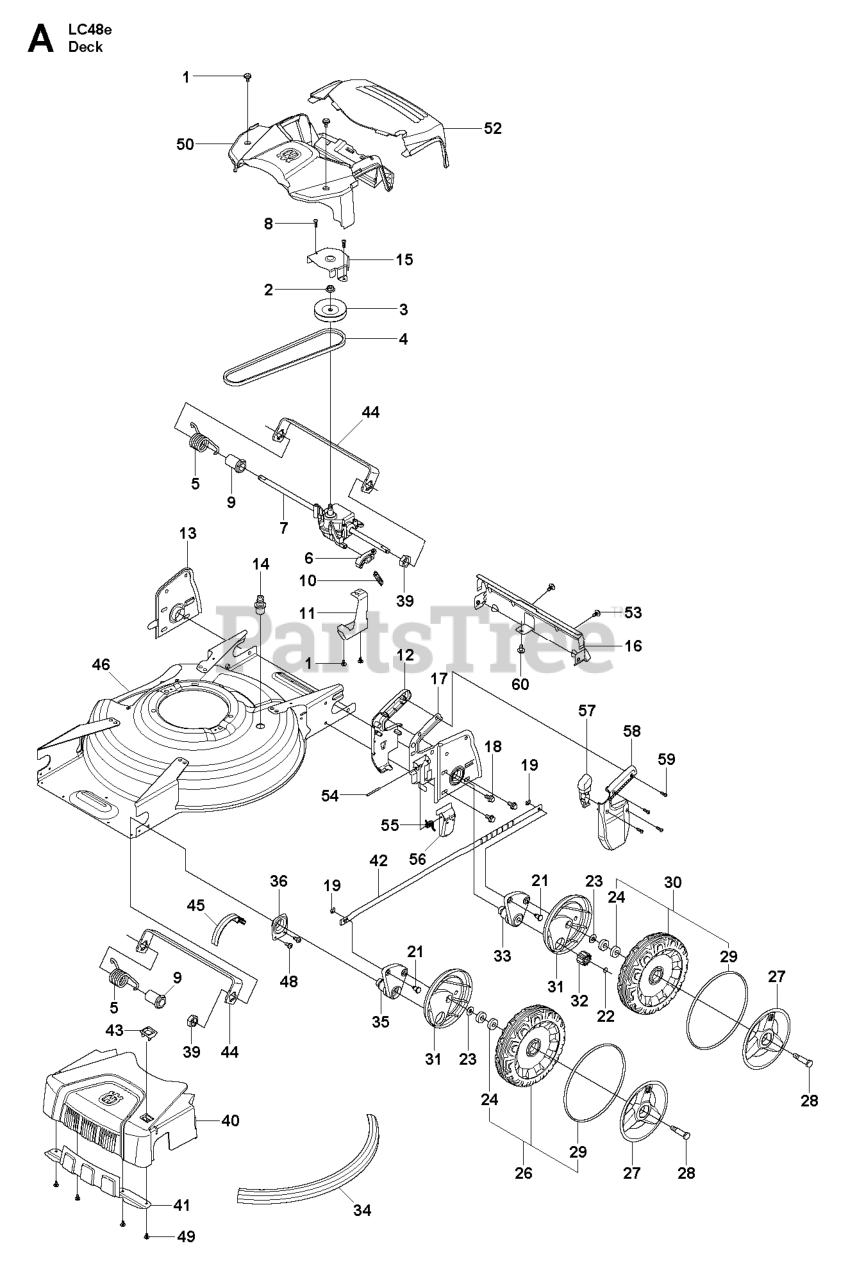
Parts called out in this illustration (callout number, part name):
1	SCREW ITXPANTT M5X10 ZPB (A00
4	BELT WRAPPED V-BELT Z 29.5
8	SCREW ITXPANT T50X16 ZN/FE (A
19	FASTENER
24	BALL BEARING
46	CHASSIS 48S A009 PAINTED
47	SCREW ITXPANTT M5X10 ZPB (A00
48	SCREW ITXPANTT M5X10 ZPB (A00
49	SCREW ITXPANTT M5X10 ZPB (A00
53	SCREW ITXPANTT M5X10 ZPB (A00
59	SCREW ITXPANT T50X16 ZN/FE (A
60	SCREW ITXPANTT M5X10 ZPB (A00
